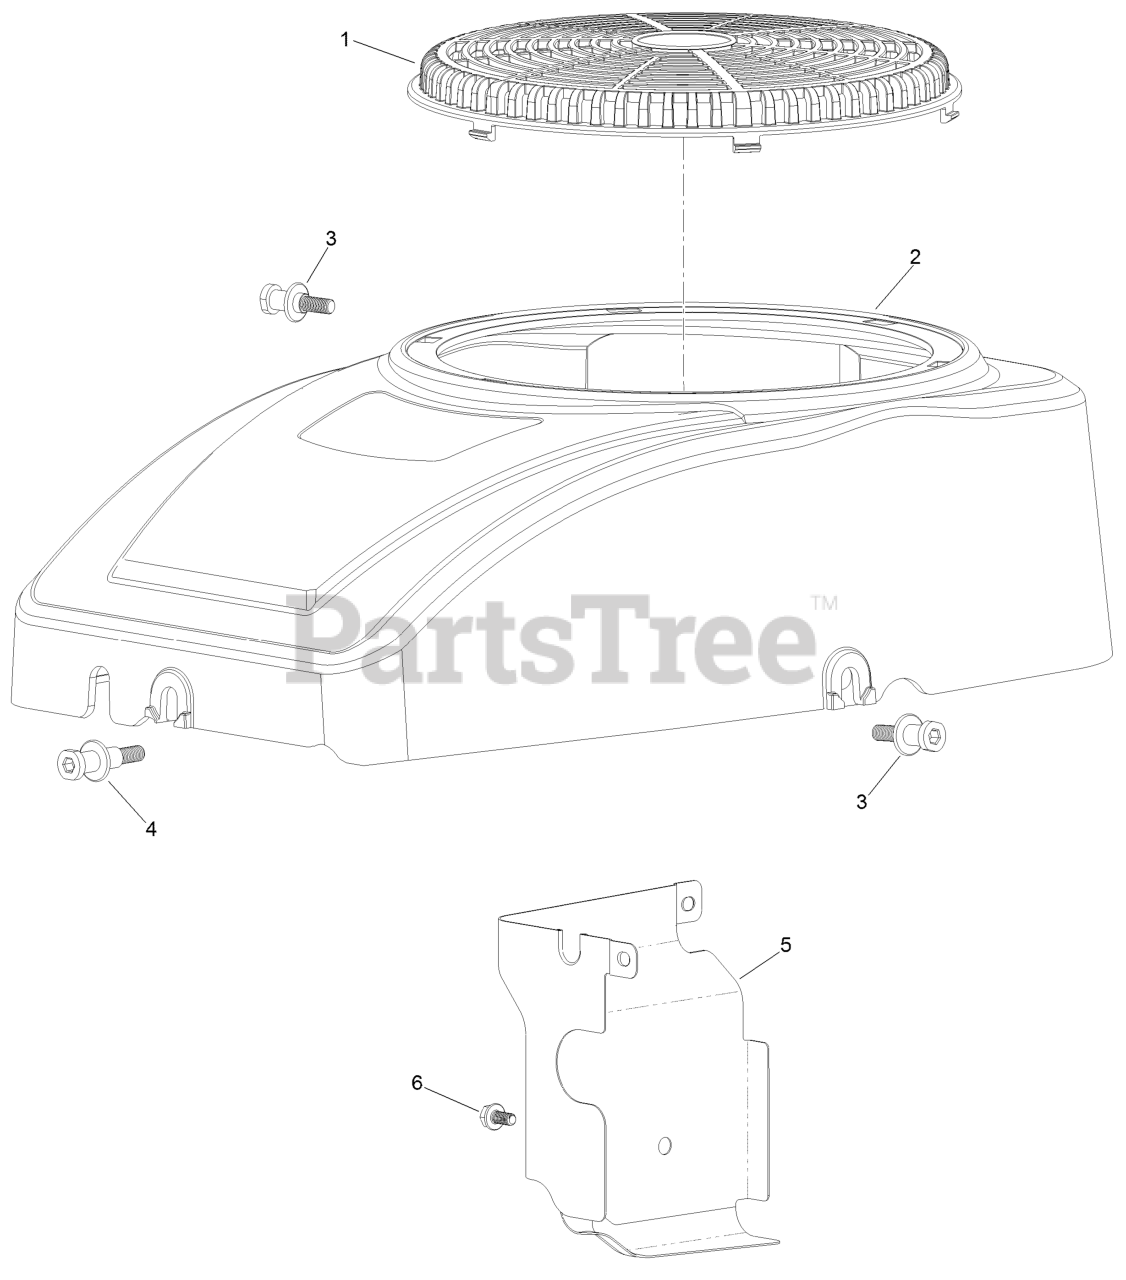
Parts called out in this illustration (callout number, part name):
1	SCREEN-STATIONARY
2	SHROUD-FAN
3	SCREW-SHOULDER, HH
4	SCREW-SHOULDER, HH
6	SCREW-HHF
